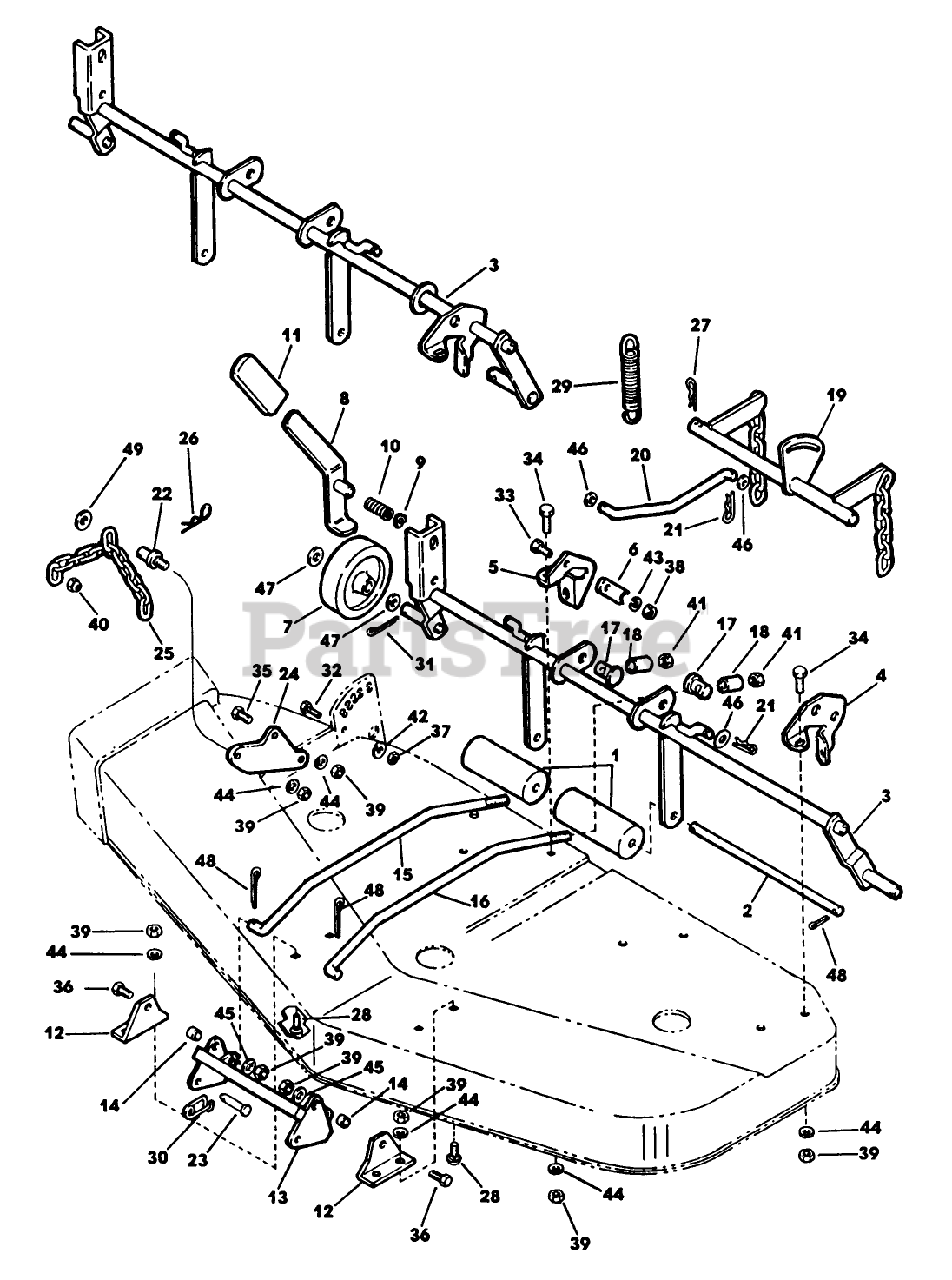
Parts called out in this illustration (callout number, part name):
1	ROLLER
2	SHAFT - ROLLER
7	WHEEL - MOWER
17	PIN - PIVOT
19	BELLCRANK ASSEMBLY *B
20	LINK - MOWER LIFT
21	PIN-HAIR
26	PIN - SPRING CLIP
30	PIN - SAFETY
32	SCREW-HH
33	SCREW - HEX
37	NUT
38	NUT SS
39	NUT
40	NUT-LOCKING
41	NUT-HEX CONE LOK
44	WASHER
45	WASHER
46	WASHER
